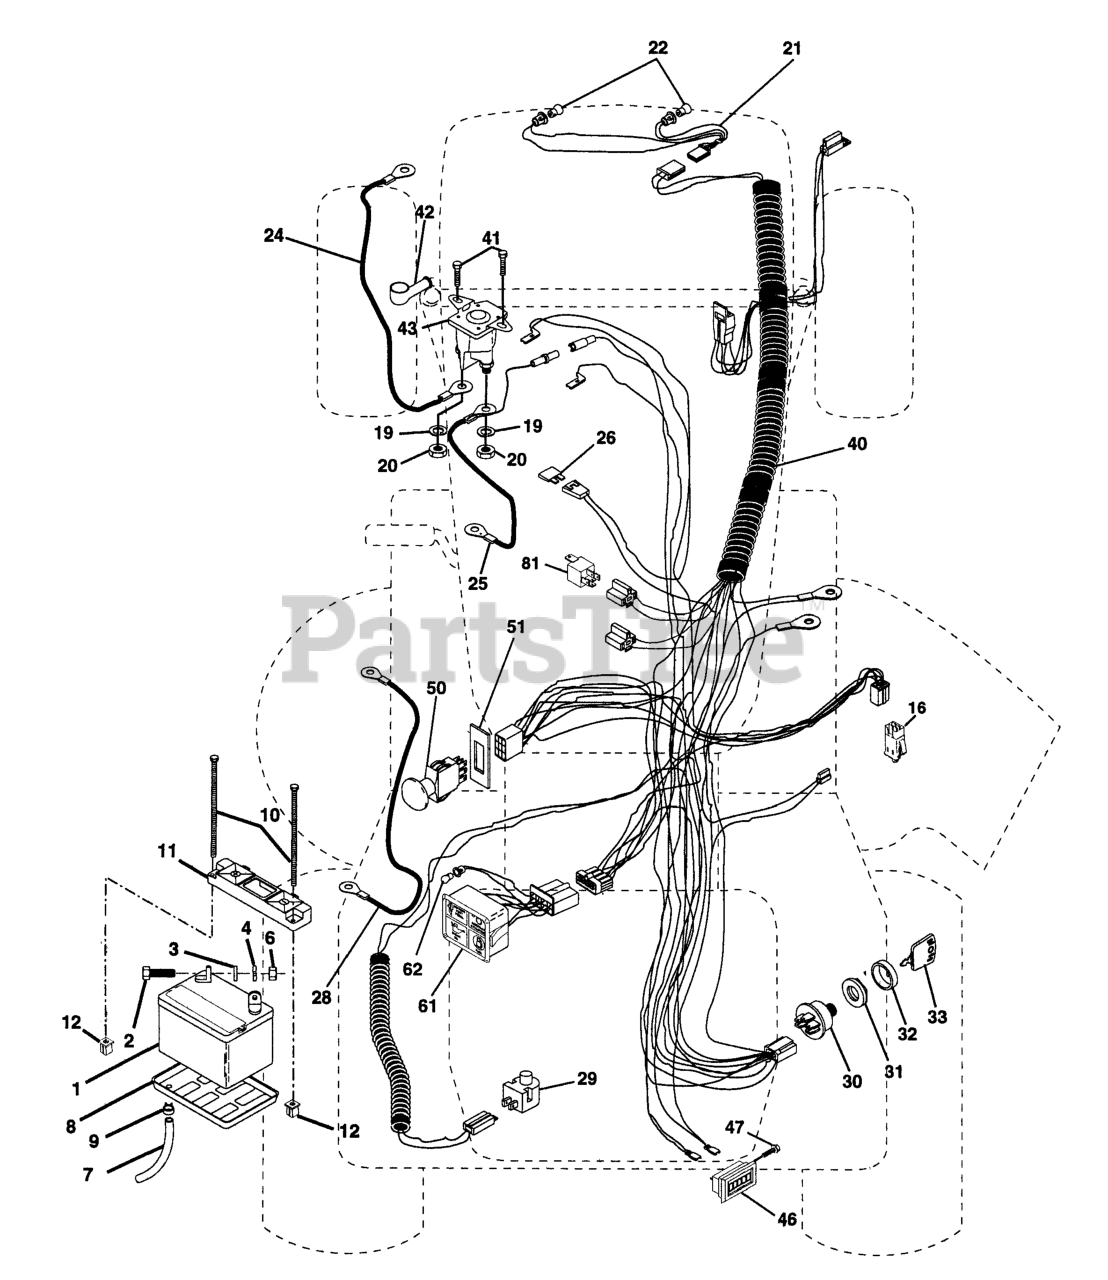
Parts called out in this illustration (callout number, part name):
1	BATTERY 12V .35 AMP
2	BOLT.HEX.1/4.X.3/4.DICHROMATE
3	LOCKWASHER
4	WASHER
6	NUT
7	PLASTIC TUBE
8	BATTERY TRAY T
9	HOSE CLAMP T
10	BOLT 1/4-20 X 7.5
11	BATTERY HOLDDOWN FRONT MOUNT
12	NUT, PUSH NYLON 1/4" BATTERY
16	SWITCH INTERLOCK
19	LOCKWASHER
20	NUT
21	HARNESS LIGHT SOCKET
24	CABLE, STARTER
25	CABLE, BATTERY
28	CABLE, GROUND
29	RP.SWITCH.PLUNGER.NC.GRAY
30	SWITCH.IGNITION.4.POSITION
31	NUT IGNITION
32	COVER SWITCH KEY
33	KEY.MOLDED.GENERIC
40	HARNESS IGN.
41	SCREW
42	TERMINAL COVER
43	SOLINOID
46	HOUR METER T
47	Screw #10-24 x 1/2
50	SWITCH PTO 3 PDT
51	FRAME RETAINING RING
61	LIGHT PACKAGE
62	BULB LIGHT T
81	RELAY.ASSY.T
